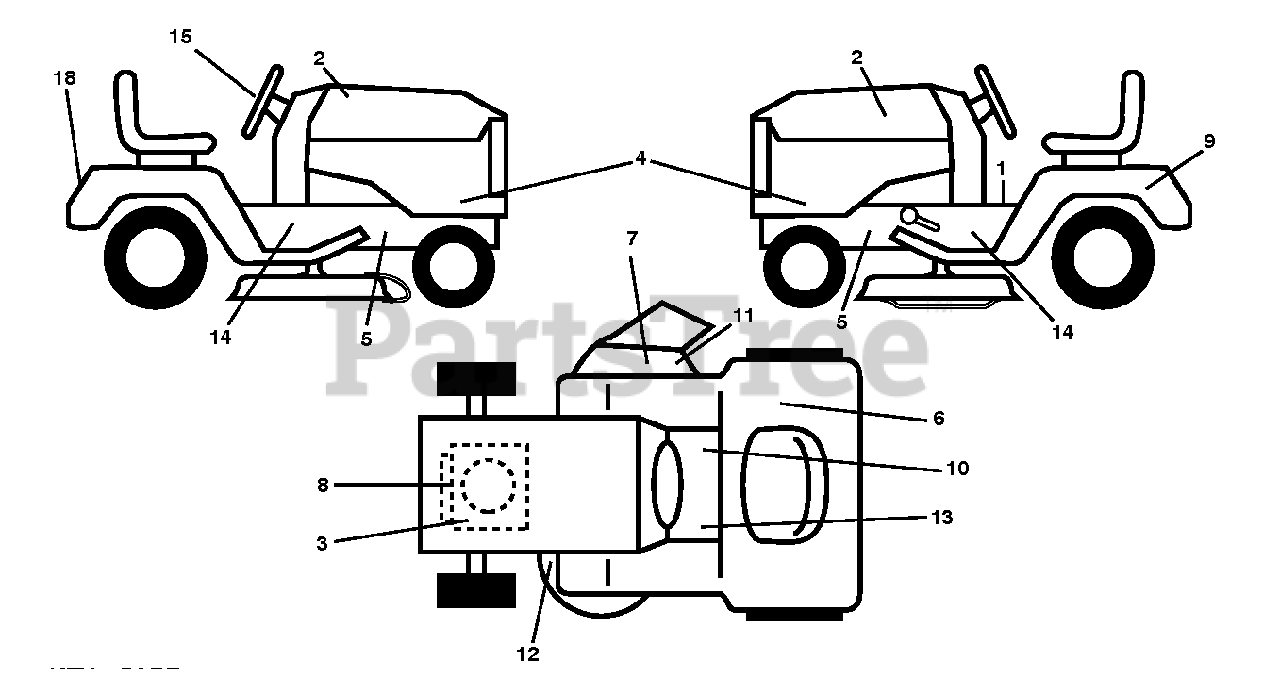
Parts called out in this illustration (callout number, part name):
6	Decal, 100 DB/CE
7	DECAL.INTERNATIONL.CUTFINGER
9	DECAL BTRY SYMBOLS
10	DECAL PARK BRAKE
11	DECAL, DEFLECT WARNING
12	DECAL V BELT SCHEMATIC
14	DECAL.CHAS.TURBO
